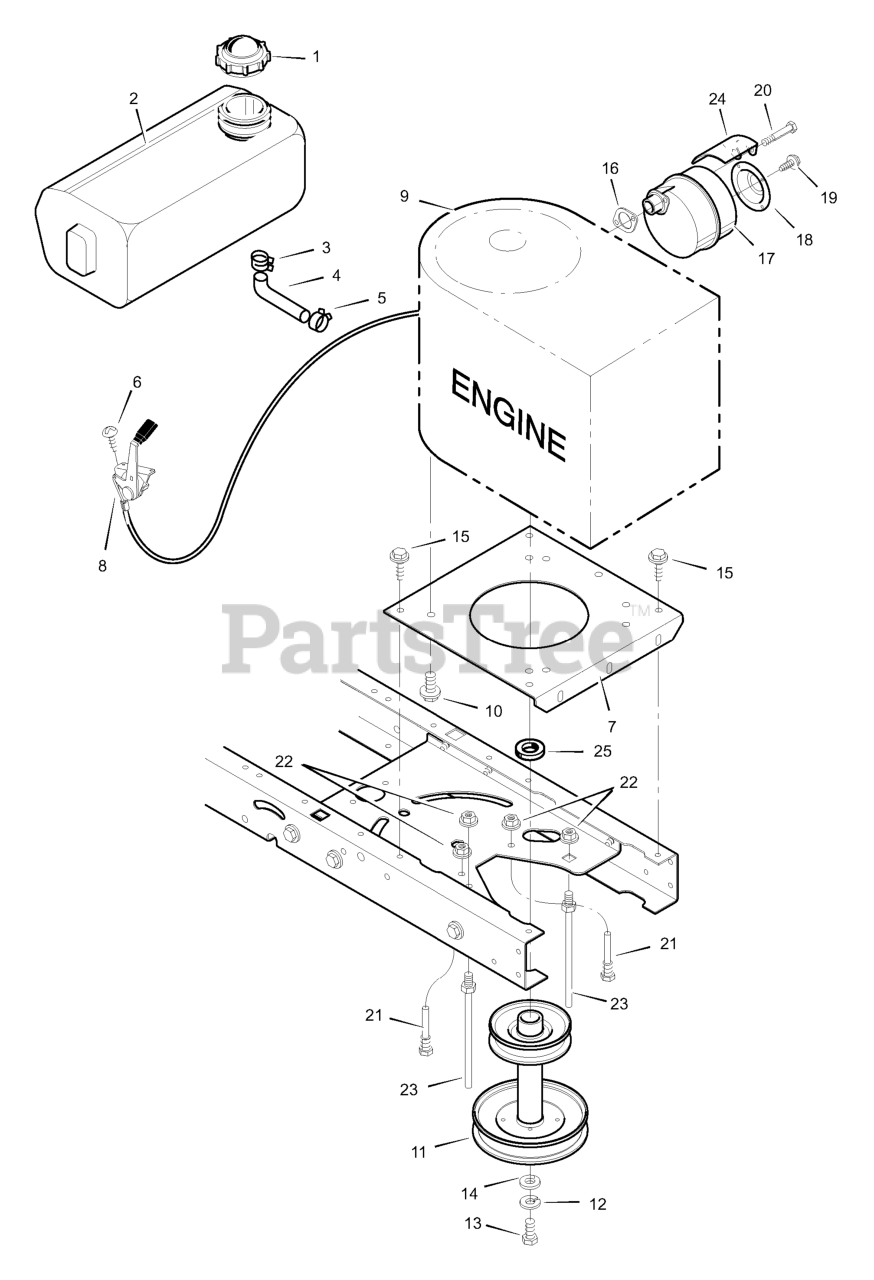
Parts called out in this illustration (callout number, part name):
1	Fuel Cap
2	Fuel Tank
3	Hose Clamp
4	Fuel Line
5	Hose Clamp
7	Plate, Engine
8	Throttle Control
9	Engine *
10	Bolt, Engine Mount
11	STACK PULLEY ASSEMBLY
12	Lockwasher
13	Bolt, Hex
16	GASKET, Exhaust
17	Muffler
18	Deflector, Muffler
20	Bolt, Hex
21	Guide, Belt
22	Nut, Flange
23	Guide, Belt
24	Shield, Heat
